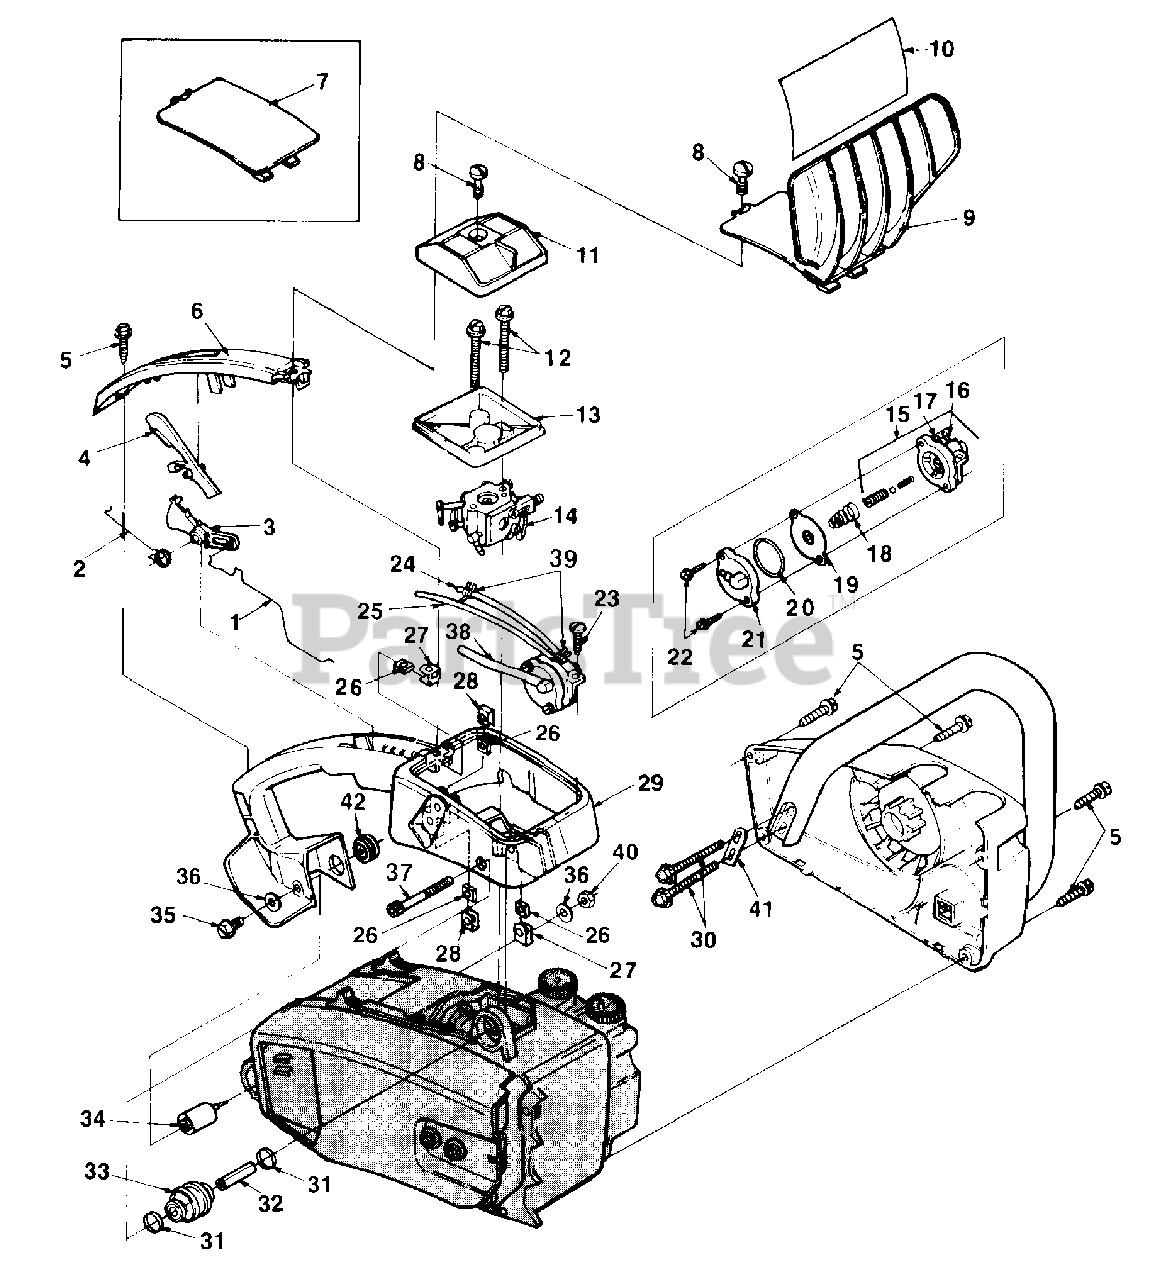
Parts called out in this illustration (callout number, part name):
1	ROD- Throttle
2	SPRING- Torsion
3	TRIGGER- Throttle
4	INTERLOCK- Trigger
5	SCREW #10 x 3/4
6	COVER- Handle
7	COVER- Air filter (240SL)
8	SCREW- Retaining
9	GUARD- Hard (w/cover) 240 HG
10	DECAL
11	FILTER ELEMENT- Top
12	SCREW- Mach hex hd. (10-24 x 1 5/8)
13	CUP- Filter
14	CARBURETOR- Zama C-1S-H4
15	BODY-Oil pump
16	FITTING- Tube
17	FITTING- Tube
18	SPRING- Oil pump
19	PLUNGER- Oil pump
20	"O" RING
21	COVER- Oil pump
22	SCREW- Plastite #18 16 x 5/8
23	SCREW- Plastite #10 x 5 8
24	TUBING- (Oil outlet) 4 l/2"
25	TUBING- (Oil inlet) 6 l/2"
26	NUT- Square 10-24
27	RETAINER- Nut
28	RETAINER- Nut
29	CHAMBER- Carburetor
30	SCREW- Hex washer (10-24 x 1 1/8)
31	RING- Vibration isolation
33	ISOLATOR
34	ISOLATOR- Shear
35	SCREW- 10-32 x 3/8
36	WASHER- Flat #10
37	SCREW- Soc. hd. cap (10-24 x 1 1/58)
38	LINE- Pulse 3 1/4"
39	CLAMP- (Oil outlet line)
40	NUT- Lock hex 10-24
41	PLATE- Handle bar
42	GROMMET
